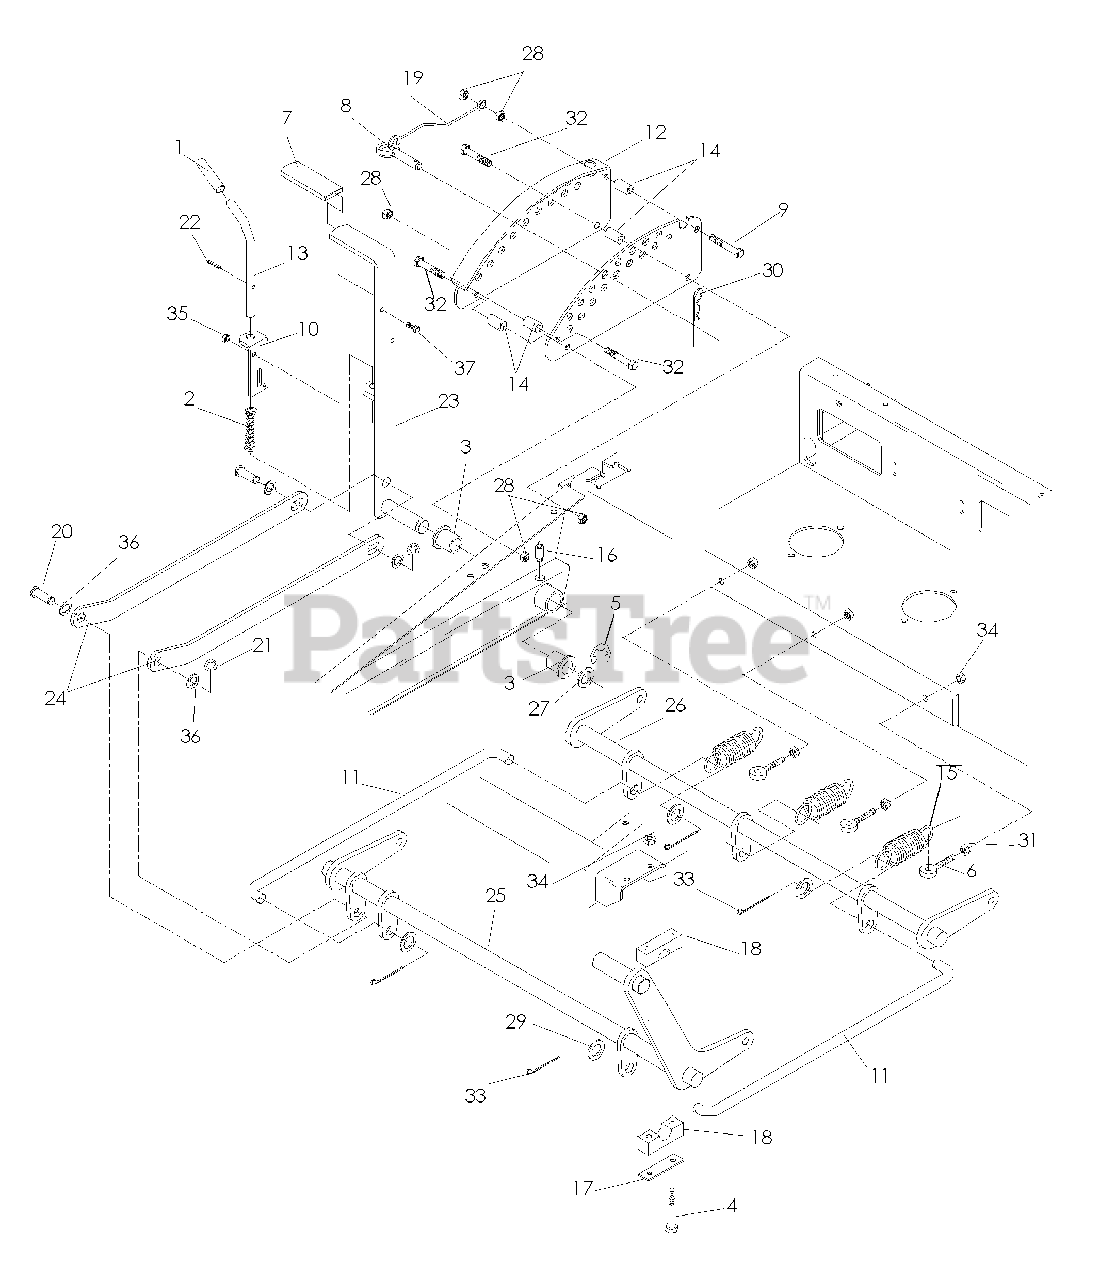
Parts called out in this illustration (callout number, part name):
3	BUSHING, FLANGED
4	HCS 5/16C X 2-3/4
5	E-RING 7/8
6	EYEBOLT, RH
8	HITCH PIN
9	SCREW 3/8C X 2 3/4 HEX CAP
10	PIN MT, UPPER
11	CONNECTING LINK
12	PLATE, HEIGHT
14	DECK LIFT SPACER
15	DECK LIFT SPRING
16	GREASE ZERK LONG
17	REINFORCEMENT BAR
18	PILLOW BLOCK
19	LANYARD
20	CLEVIS PIN
21	E-RING 5/8
23	LIFT LEVER WELDMENT
24	STRAP, LIFT
25	SHAFT, LIFT, FRONT
26	SHAFT, LIFT, REAR
27	BSHG .875 X 1.375 X .074 ZD
28	NUT 3/8-16 NYLOC
29	WASHER 5/8 FLAT
30	HAIRPIN #4
31	NUT 5/16C WHIZ
32	HCS 3/8C X 2 1/4
33	COTTER PIN
34	NUT 5/16 NYLOC
35	NUT 1/4C CENTER LOCK
36	BUSHING
37	HCS 1/4C X 3/4 HCS
